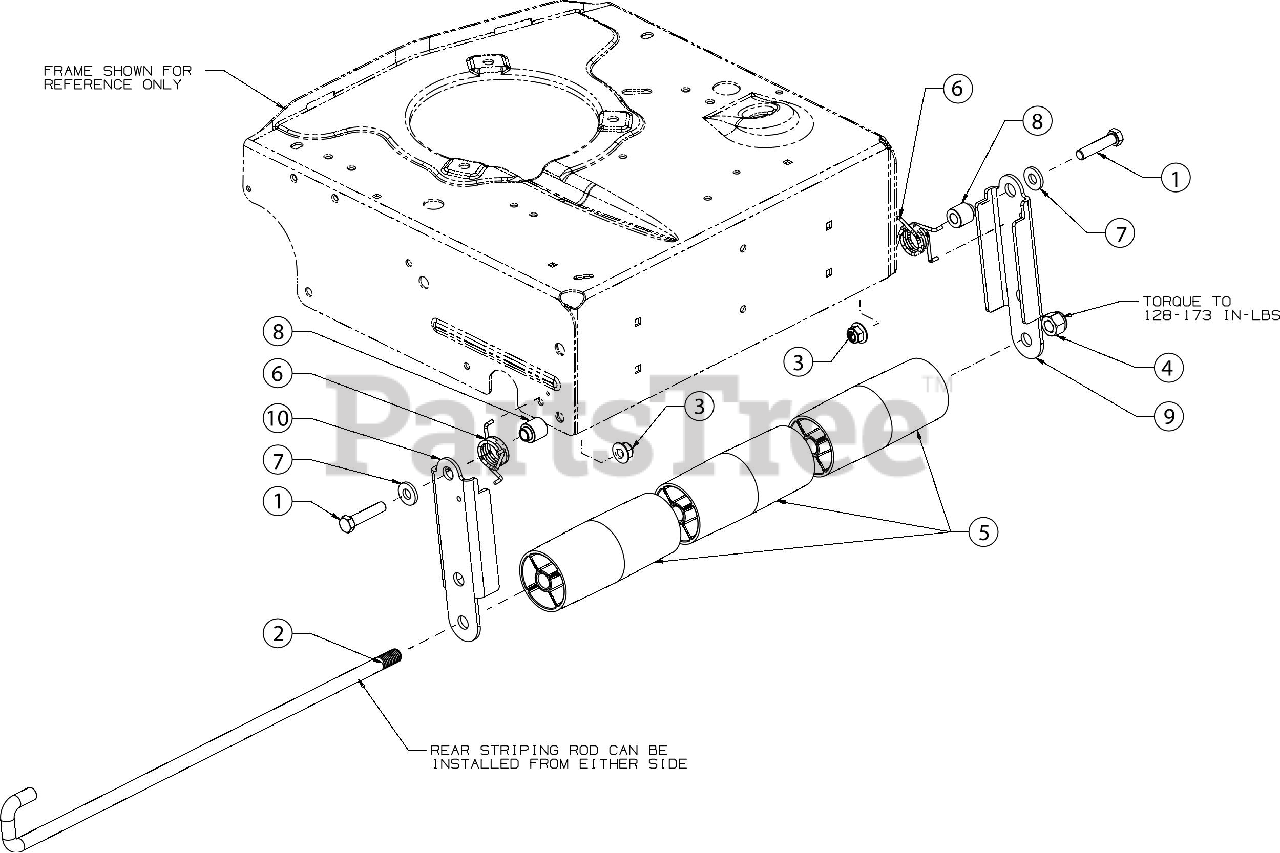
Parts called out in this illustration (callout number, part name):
1	HEX SCREW 3/8-16 x 1.75 GR5
4	HEX LOCK NUT NYLON
6	TORSION SPRING
7	FLAT WASHER
8	CASTER HUB
